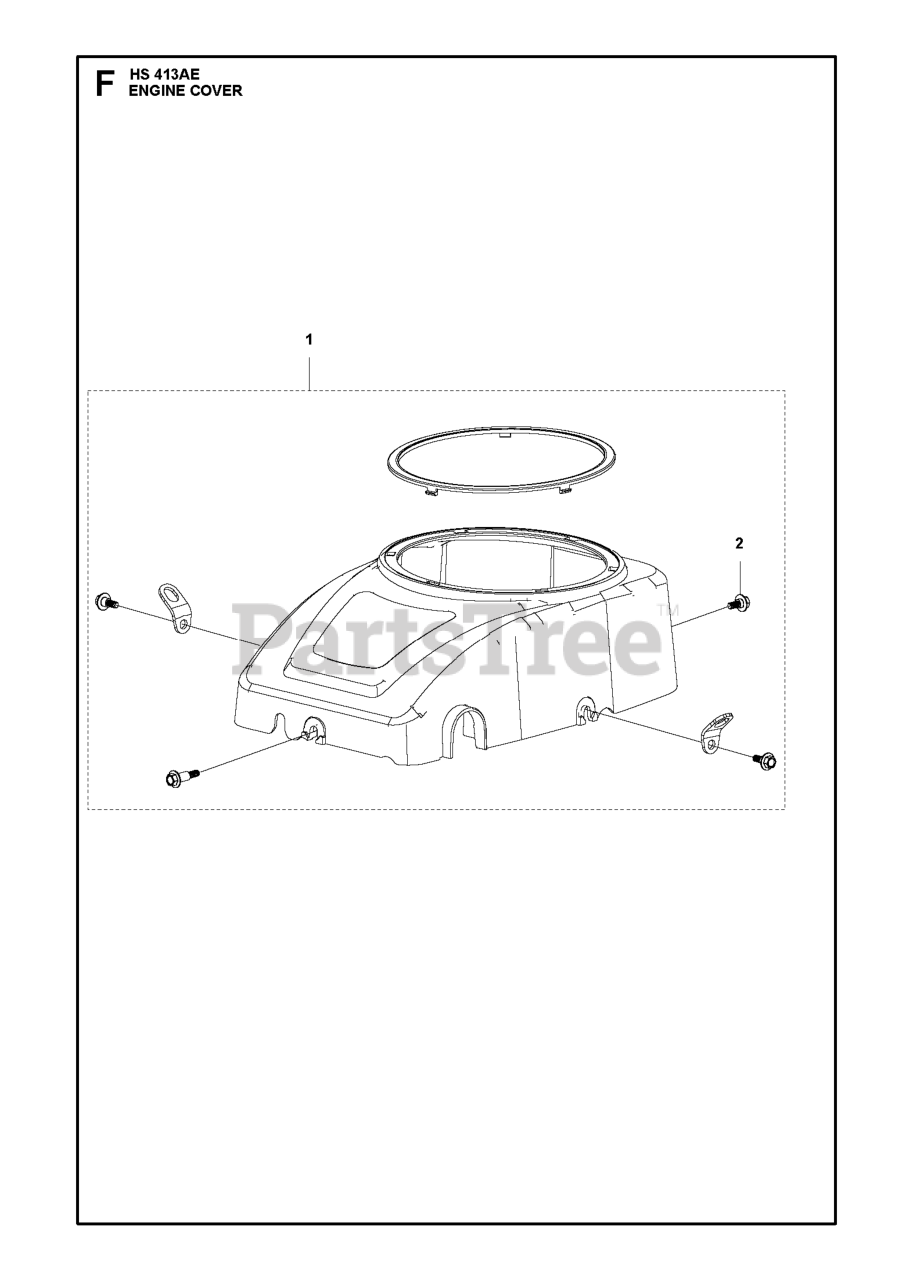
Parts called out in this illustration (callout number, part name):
1	CYLINDR.HEAD.SRV.KIT W/GASKET
2	Husqvarna TBD
2	KIT.PUSH.ROD.SRV(SK208-1001)
3	VALVE COVER ASSEMBLY
4	KIT.CYLINDER.SRV(SK208-1300)
5	KIT.PISTON.SRV(SK208-1400)
6	KIT.CONNECT.ROD.SRV(SK208-1500
7	KIT.CAMSHAFT.208CC.LCT
8	RP KIT.FLYWHEEL.SERVICE
9	FLYWHEEL FAN 420586
10	RP KIT.CRANKSHAFT.SRV
11	KIT.AIRFLTR.ASY.SRV(SK208-2002
12	KIT.SERV.PAP.FILTER(SK208-2012
13	KIT.49STATE.MUFFLER(SK208-2101
14	KIT.49STATE.FUEL.TK(SK208-2200
15	FUEL.PETCOCK.LQA.3/16".LCT
16	KIT.49STATE.FUEL.TK(SK208-2300
17	KIT.CARBURETOR.SERV(SK20-2401)
18	KIT.IGNITION.COIL
19	KIT.IGNITION.(CDI BOX)
20	KIT.SPARK.PLUG.SRV(SK1500)
21	KIT.ENGINE.ON/OFF.LCT.208CC
23	KIT.FUEL.HOSE(SK208-6000)
24	KIT.THROTTLE.CONTRL(SK206-2800
25	KIT.GOVERNOR.GEAR(SK208-2900)
26	RP_IT.GOVERNOR.ARM(SUMMER ENG)
27	KIT.GOVERNOR.CRANK(SK208-3100)
28	KIT.RECOIL.STARTER(HEX) BLACK
29	KIT.STARTER.CUP.SRV(SK208-3300
30	KIT.BLOWER.HSG.SRV(SK208-3400)
31	CRANKCASE COVER ASSY
32	KIT.SEAL.SERVICE(SK208-3900)
34	RP KIT.SPARK.PLUG.BOOT
36	GASKET.KIT.208CC(SK2084300.1)
37	DIPSTICK SMALL
